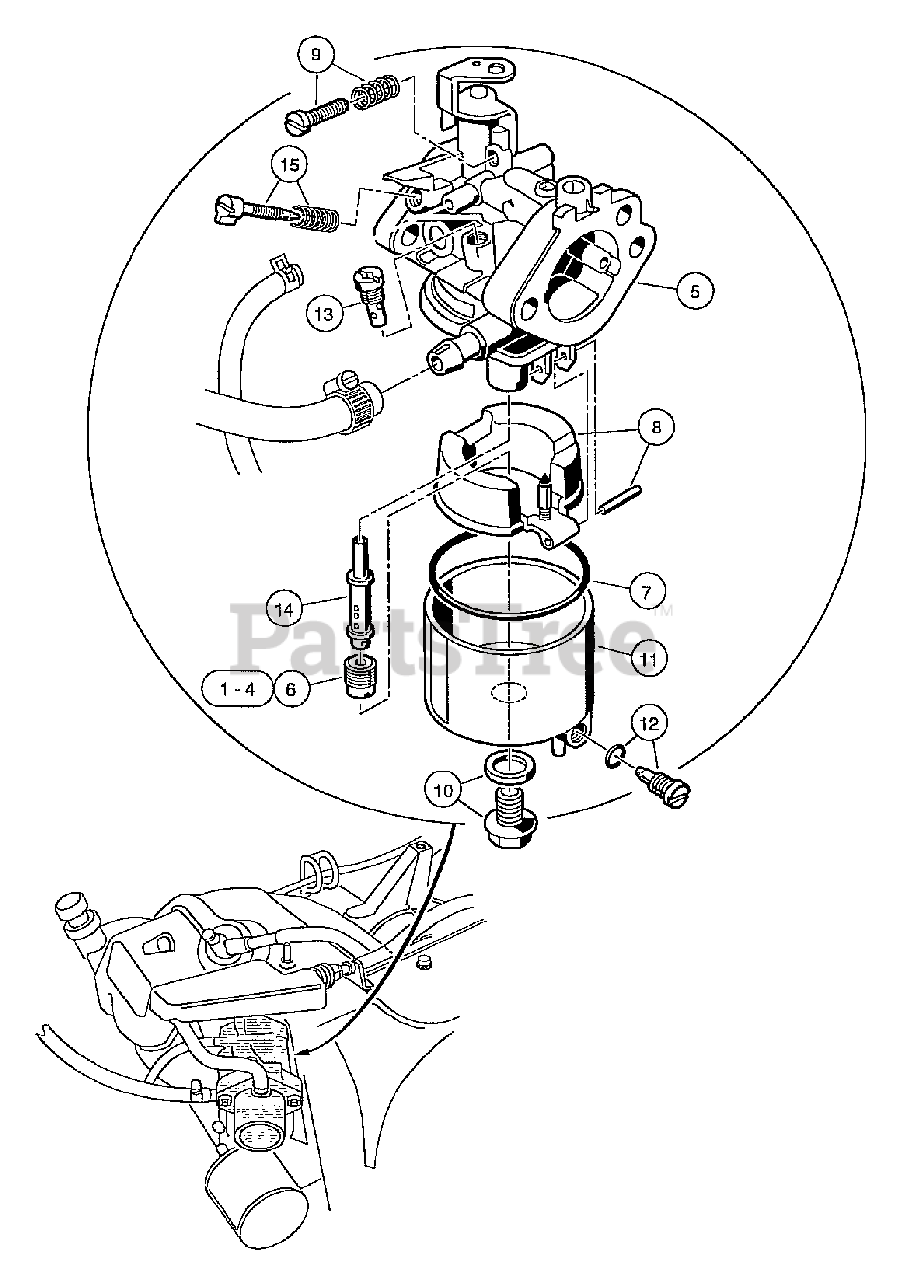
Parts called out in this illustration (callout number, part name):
1-4	Jet, Altitude, # 75
1-4	Jet, Altitude, # 78
1-4	Jet, Altitude, # 80
1-4	Jet, Altitude, # 82
5	Carburetor, FF350D
6	Jet, Altitude, # 85
7	Gasket, Carburetor Bowl OHV
8	Float Assembly
9	Screw Assembly
11	Chamber Assembly, Float
12	Screw Assembly
13	Jet, #40 Pilot
14	Nozzle, Main
15	Assembly, Pilot Alr Screw
